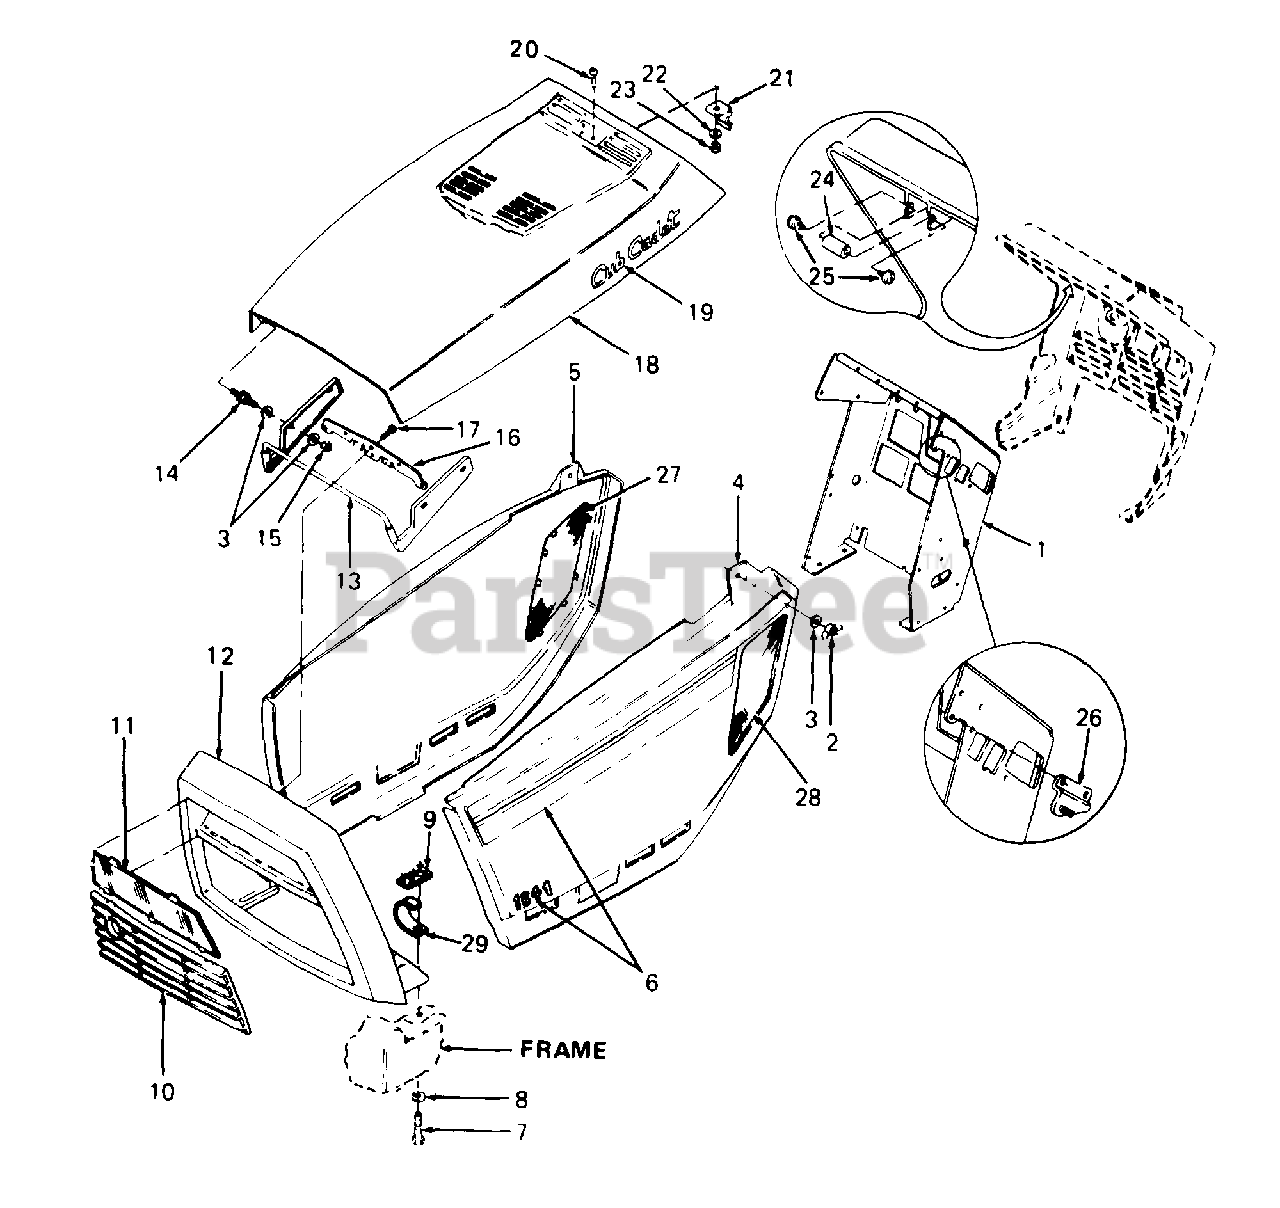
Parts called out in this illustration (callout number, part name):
3	Washer, Flat, .251 X .62 X .052 Thk
4	Panel, LH Side
5	Panel, RH Side
6	Graphics Kit, LH Side Panel
7	Screw, Hex Cap, 5/16-1B X 1.0 Lg GR5
8	Washer, Lock, 5/16
9	Retainer, Grille Housing
10	Grille, Insert
11	Grille, Lens
12	Grille Hsg
15	Nut, Hex Patch Lock, 1/4-20
18	Hood
19	Graphic, Cub Cadet Script w/Studs
20	Screw, Truss Hd, O8-32 X .38 Lg
21	Clip, Hood Latch
22	Washer, Flat, .16 X .38 X .045 Thk
23	Nut, Hex Keps, #8-32
24	Pin, Latch
25	Screw, Phillips Hd Truss Mach, 1/4-20 X .50 Lg
